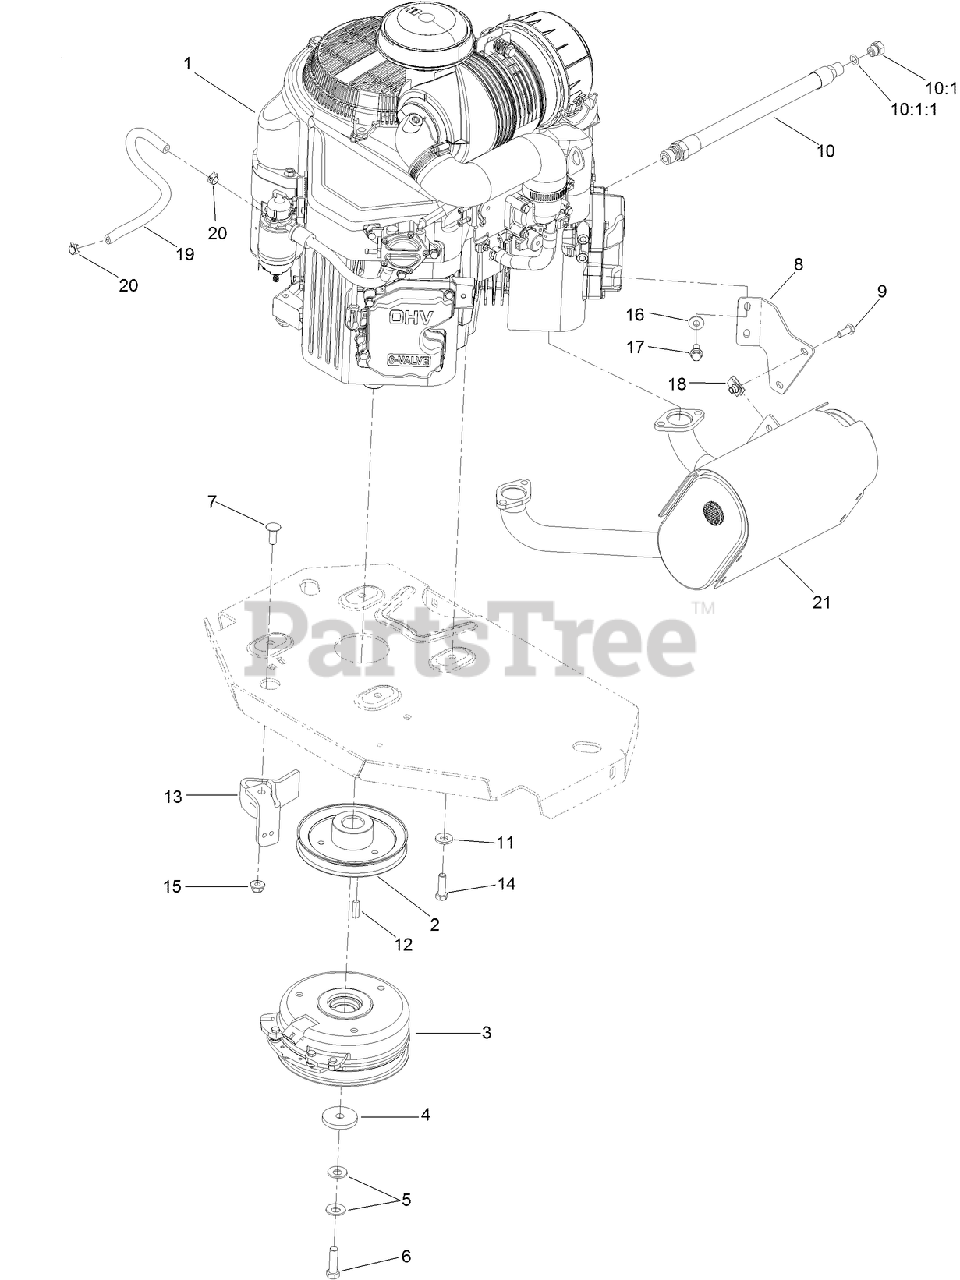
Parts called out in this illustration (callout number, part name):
2	SHEAVE
3	CLUTCH KIT
4	WASHER-CLUTCH
5	WASHER-SPRING
6	SCREW-HH
7	SCREW-CARR
8	BRACKET-MUFFLER
9	SCREW-HH
10	ENGINE OIL DRAIN HOSE ASM
10:1	PLUG-HH
10:1:1	O-RING
11	WASHER-BELLEVILLE
13	CLUTCH-ANCHOR
14	SCREW-HH
15	NUT-HF, NI
16	WASHER-SPRING
17	SCREW-HHF
18	NUT-U
19	HOSE-FUEL
20	CLAMP-HOSE
21	MUFFLER
